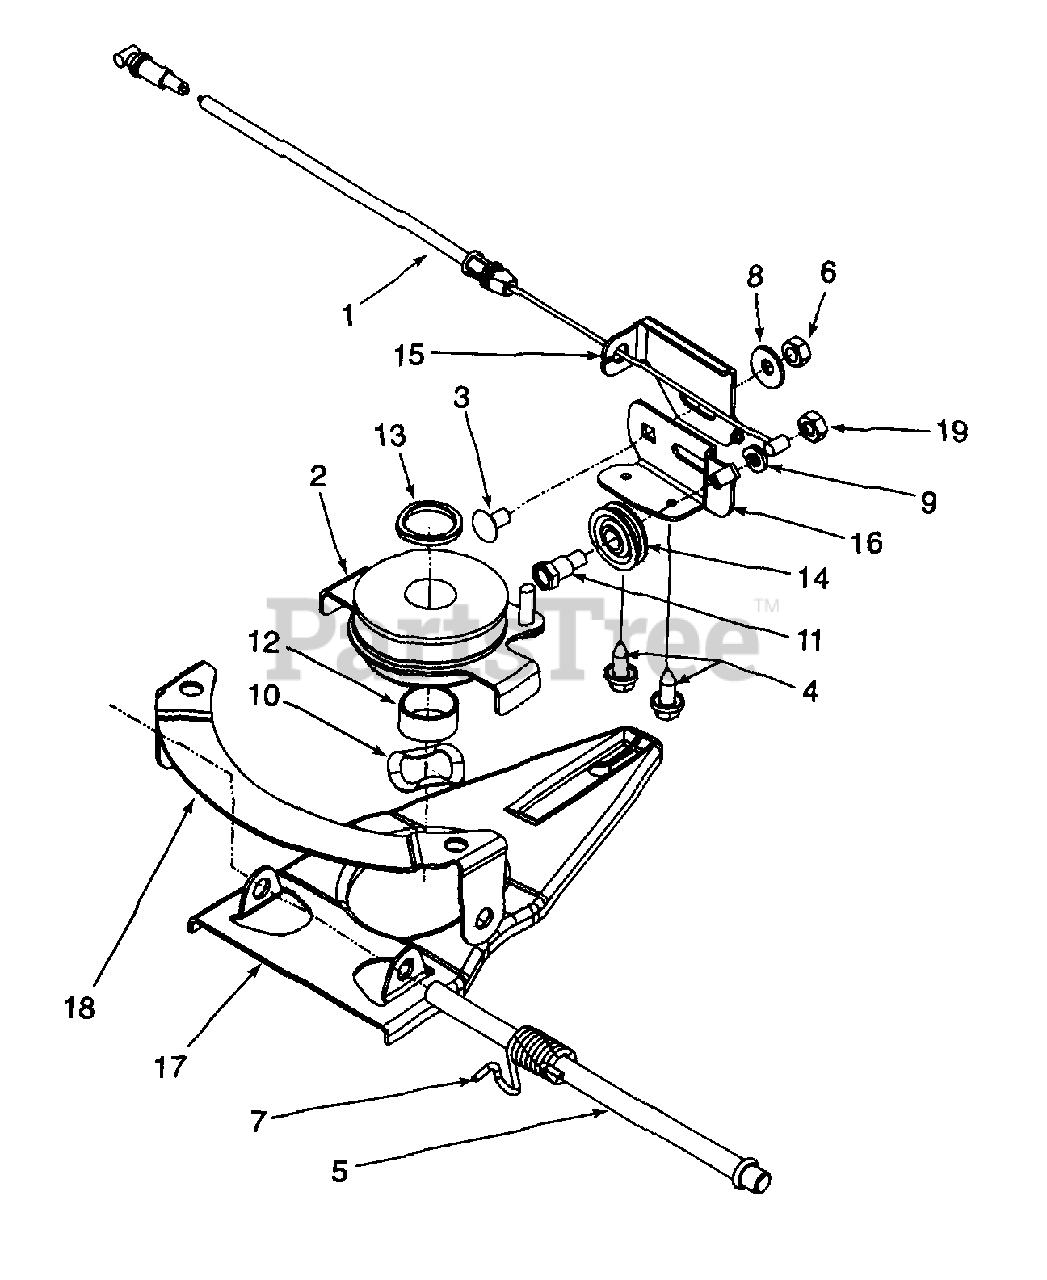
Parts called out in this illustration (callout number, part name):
1	6 Spd. Cable
2	Pulley Ass'y Multi - Spd.
3	Scr. 1/4-20 x .50 Carr.
4	Scr. AB 1/4-14 x .625 Hxinwsh
5	Pivot Shaft
6	Nut 1/4-20
7	Torsion Spring LH
8	Bell Wash. .265 X .75 X .062
9	Lock Wash. 1/4 Reg Duty
10	Wave Wash. 1.38 x .88 x .029
11	Shld.Scr. .375 x 1/4-14AB
12	Slev Spcr .88 ID x 1.00 OD x .48
13	Slev Spcr .66 ID x 1.13 ID x .12
14	Roller Cable
19	Hex Nut 1/4-28
